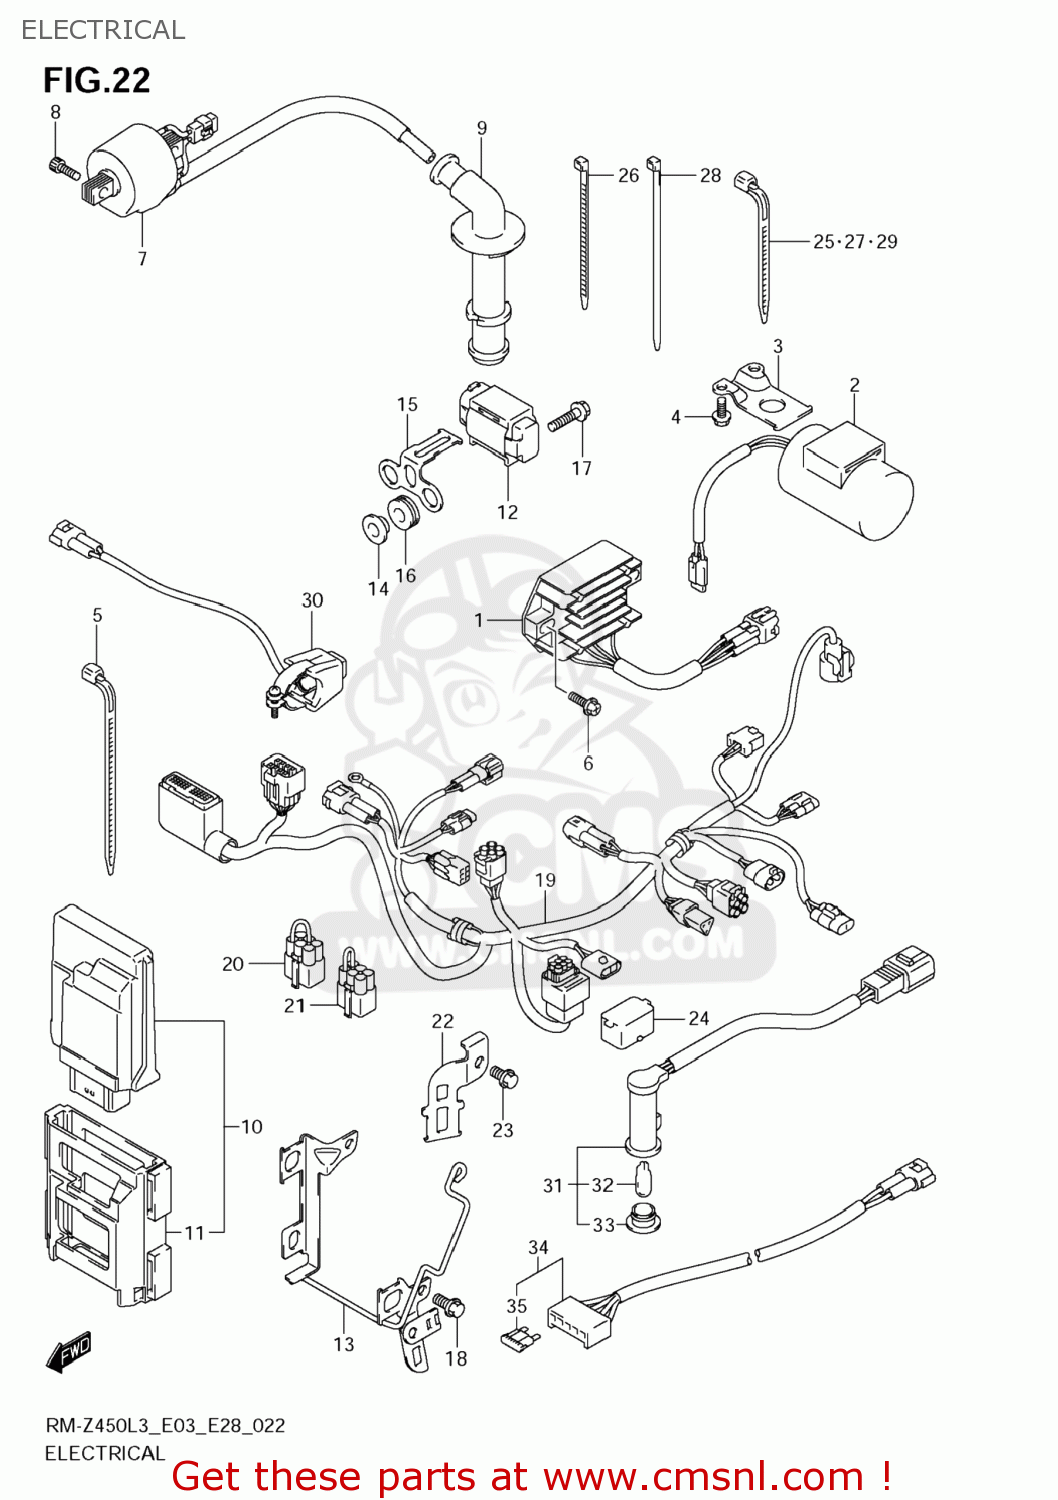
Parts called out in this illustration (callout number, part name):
1	RECTIFIER ASSY
2	CONDENSER ASSY
3	BRACKET,CONDENSER
4	BOLT(6X10)
5	CLAMP(L:235)
6	SCREW
7	COIL ASSY,IGNITION
8	BOLT
9	CAP ASSY,SPARK PLUG
10	CONTROL UNIT,FI
11	CUSHION,FI CONTROL UNIT
12	SENSOR ASSY,FUEL CUT
13	BRACKET,FI CONTROL UNIT
14	SPACER(6.2X8.4X10.9)
15	BRACKET,FUEL CUT SENSOR
16	CUSHION
17	BOLT(6X30)
18	BOLT
19	HARNESS,WIRING
20	WIRE,SHORT
21	WIRE,SHORT
22	BRACKET,COUPLER
23	BOLT
24	CAP,TS
25	CLAMP(L:95)
26	CLAMP(L:95)
27	CLAMP(L:125)
28	CLAMP(L:145)
29	CLAMP(L:165)
30	SWITCH ASSY,ENGINE STOP
31	LAMP ASSY,FI INDICATOR
32	BULB(12V3.4W,T10)
33	LENS(RED)
34	WIRE,BATTERY
35	FUSE(10A)
